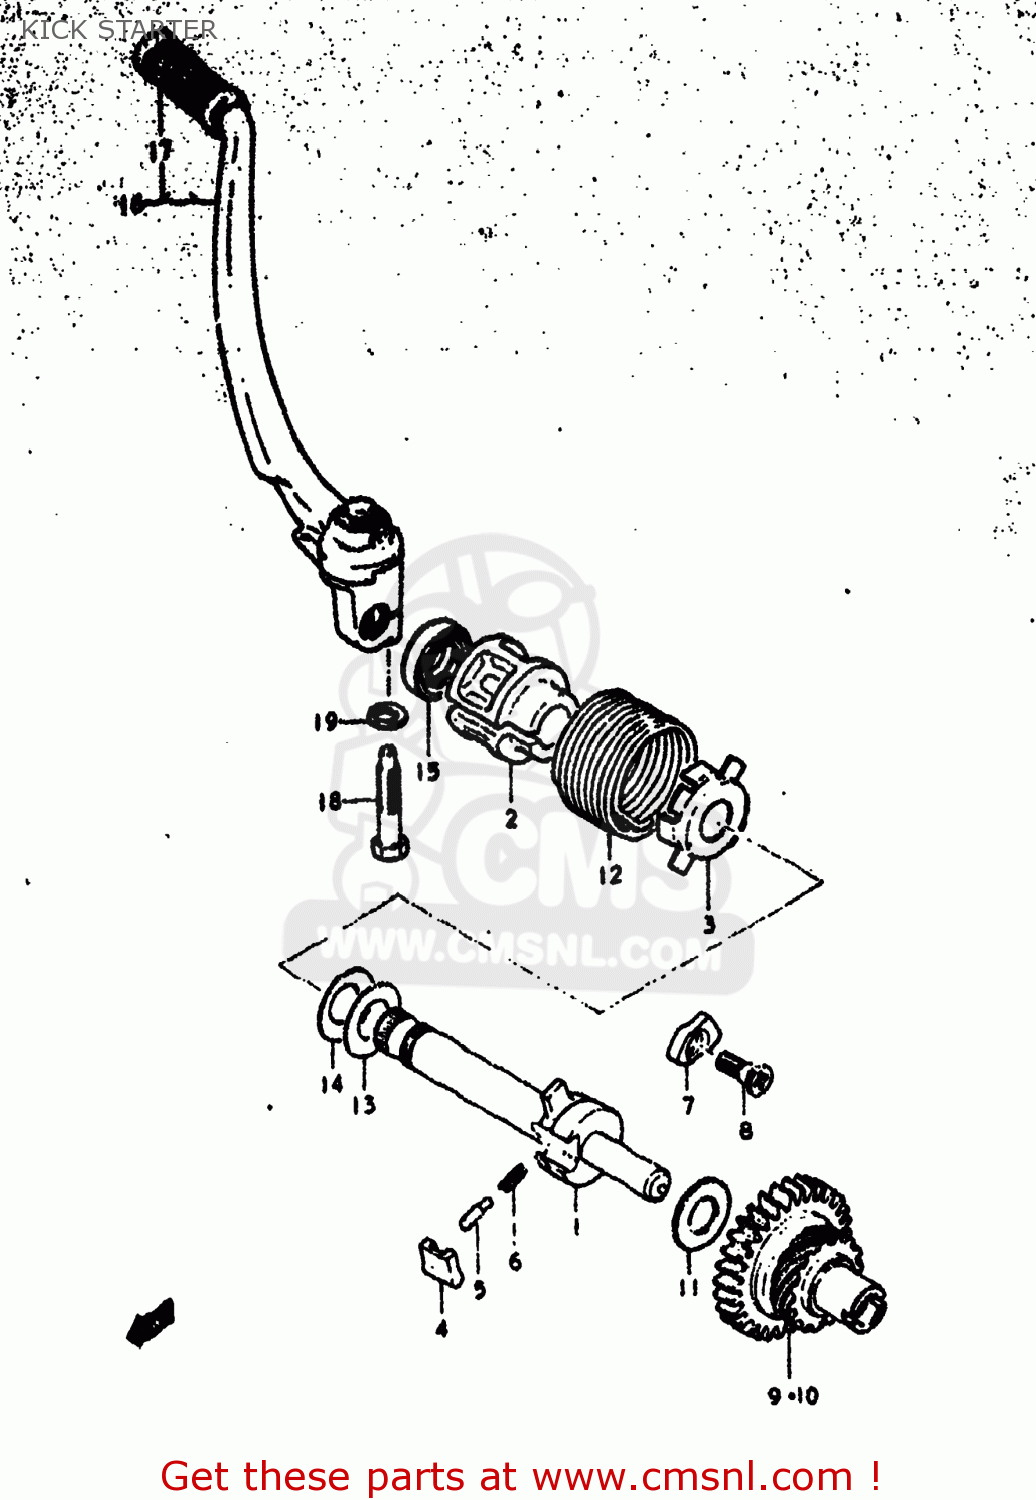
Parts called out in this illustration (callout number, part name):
1	SHAFT,KICK STARTER
2	GUIDE,KICK SHAFT SPRING
3	HOLDER,KICK SHAFT SPRING
4	PAWL,KICK STARTER
5	PIN(5X15.5)
6	SPRING
7	LIFTER,KICK STARTER PAWL
8	SCREW(6X19)
9	GEAR,KICK STARTER DRIVE
10	GEAR,KICK STARTER DRIVE
11	WASHER
12	SPRING
13	WASHER(16X30X0.5)
14	WASHER
15	SEAL,OIL(16X30X8)
16	LEVER ASSEMBLY,KICK STARTER
17	RUBBER,KICK STARTER PEDAL
18	BOLT
19	LOCK WASHER
